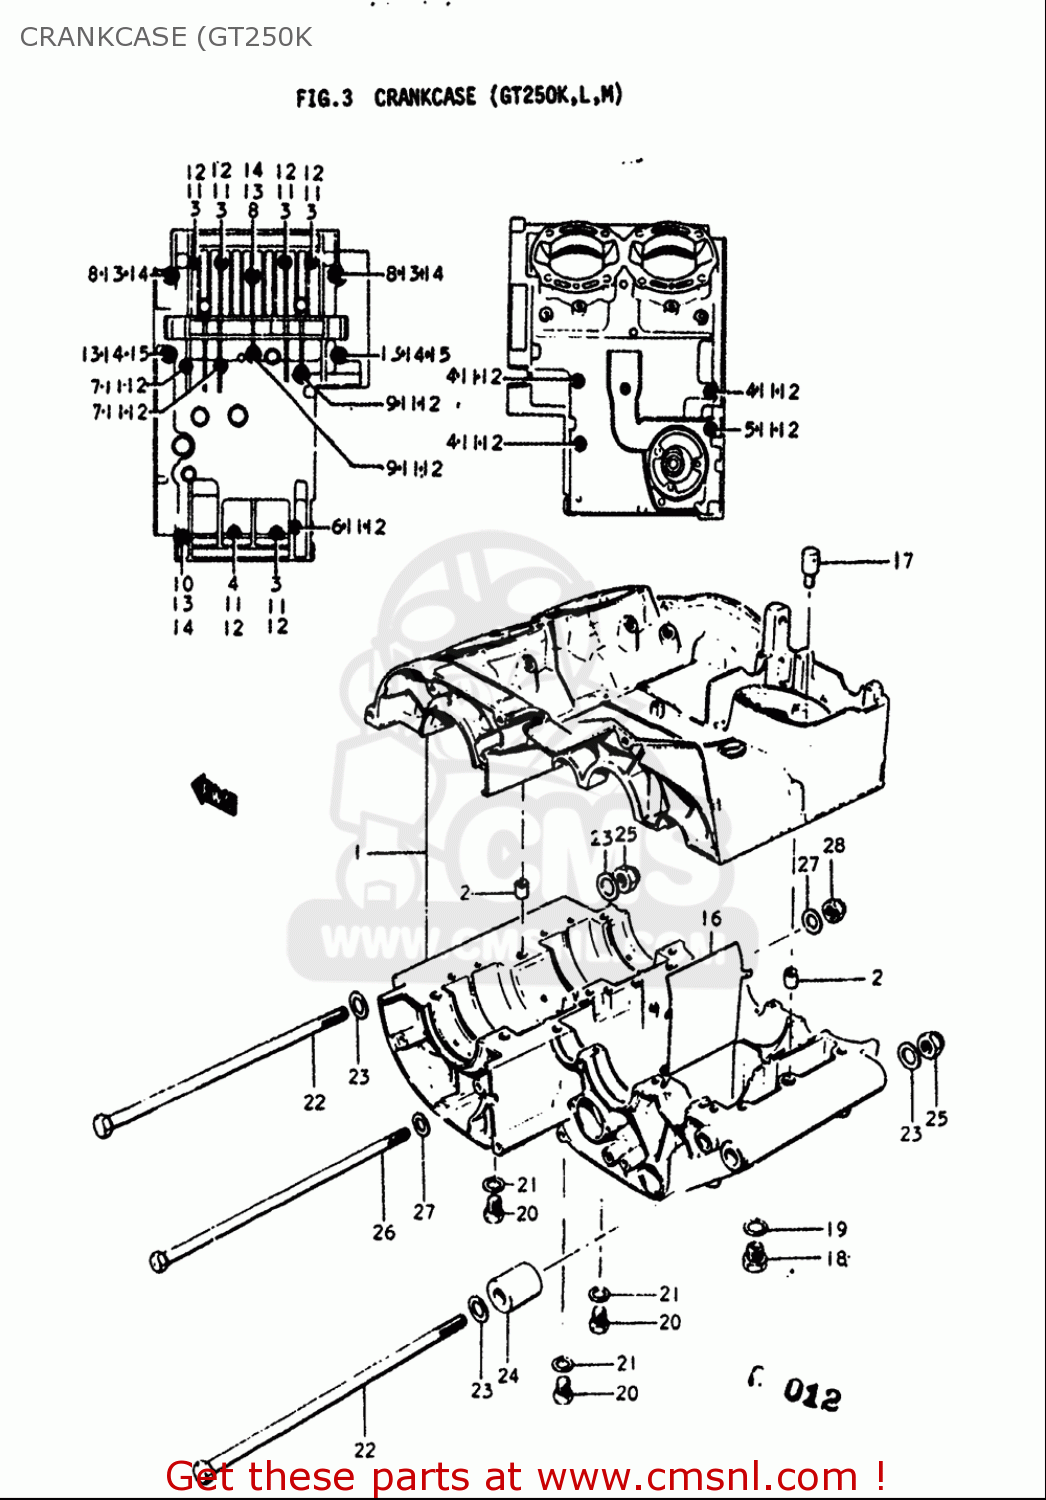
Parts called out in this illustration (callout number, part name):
2	PIN
3	BOLT
4	BOLT(6X60)
5	BOLT(6X65)
6	BOLT
7	BOLT
8	BOLT
9	BOLT
10	BOLT
11	WASHER,LOCK
12	WASHER
13	WASHER,LOCK
14	WASHER
15	BOLT 8X100
17	PLUG,T/M BREATHER
18	PLUG(MAGNETO)
19	GASKET(14X19.2X2) (NAS)
20	PLUG
21	GASKET(10X14X3.6) (NAS)
23	WASHER
24	SPACER
25	NUT
27	WASHER
28	NUT
